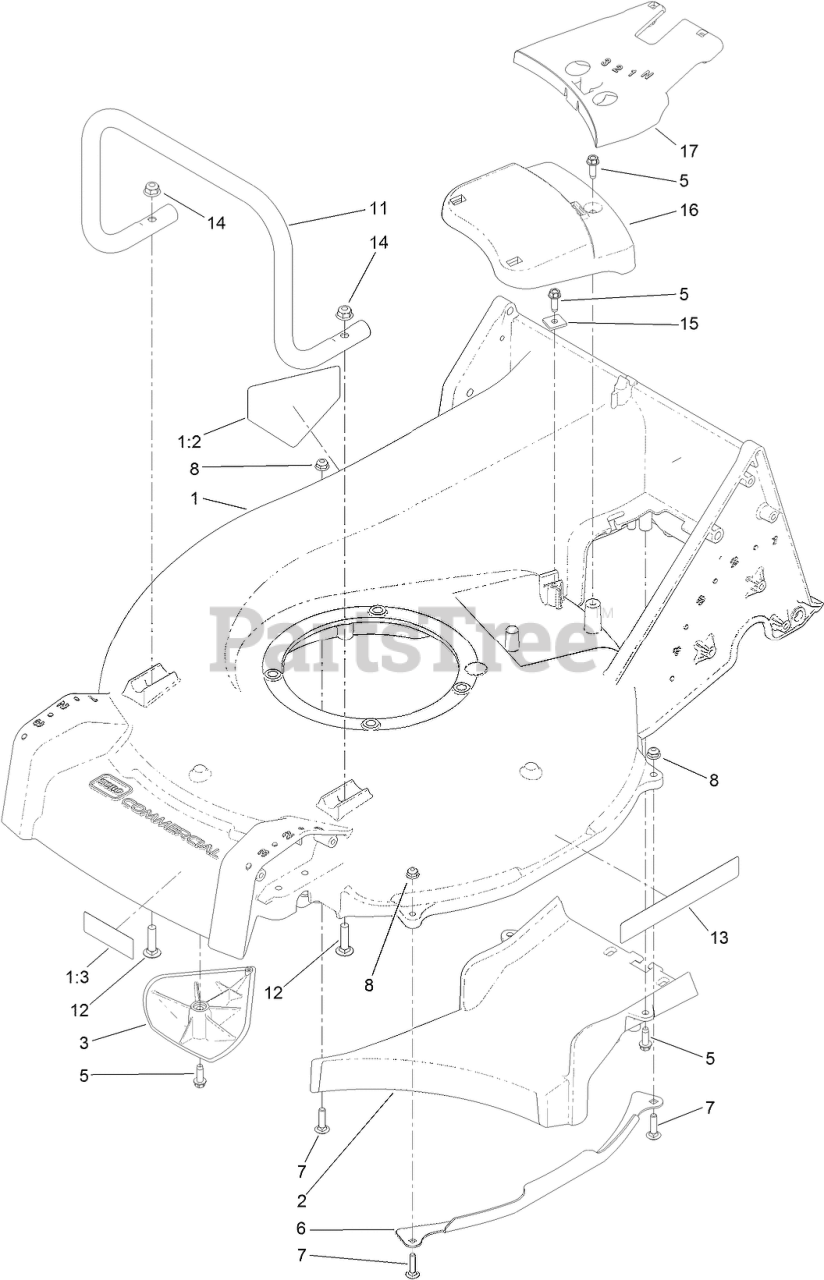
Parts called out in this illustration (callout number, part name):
1	HOUSING ASM
1:2	DECAL-DANGER
1:3	DECAL-BLADE
2	FLOOR-CHUTE
3	KICKER
5	SCREW-HWHTF
6	GUARD-SIDE, DECK
7	SCREW-CARR
8	NUT-HF
11	GUARD-ENGINE
12	SCREW-CARR
13	DECAL-RECYCLER
14	NUT-HF, NI
15	CLAMP-CABLE
16	COVER-BELT, FRONT
17	COVER-BELT, REAR
